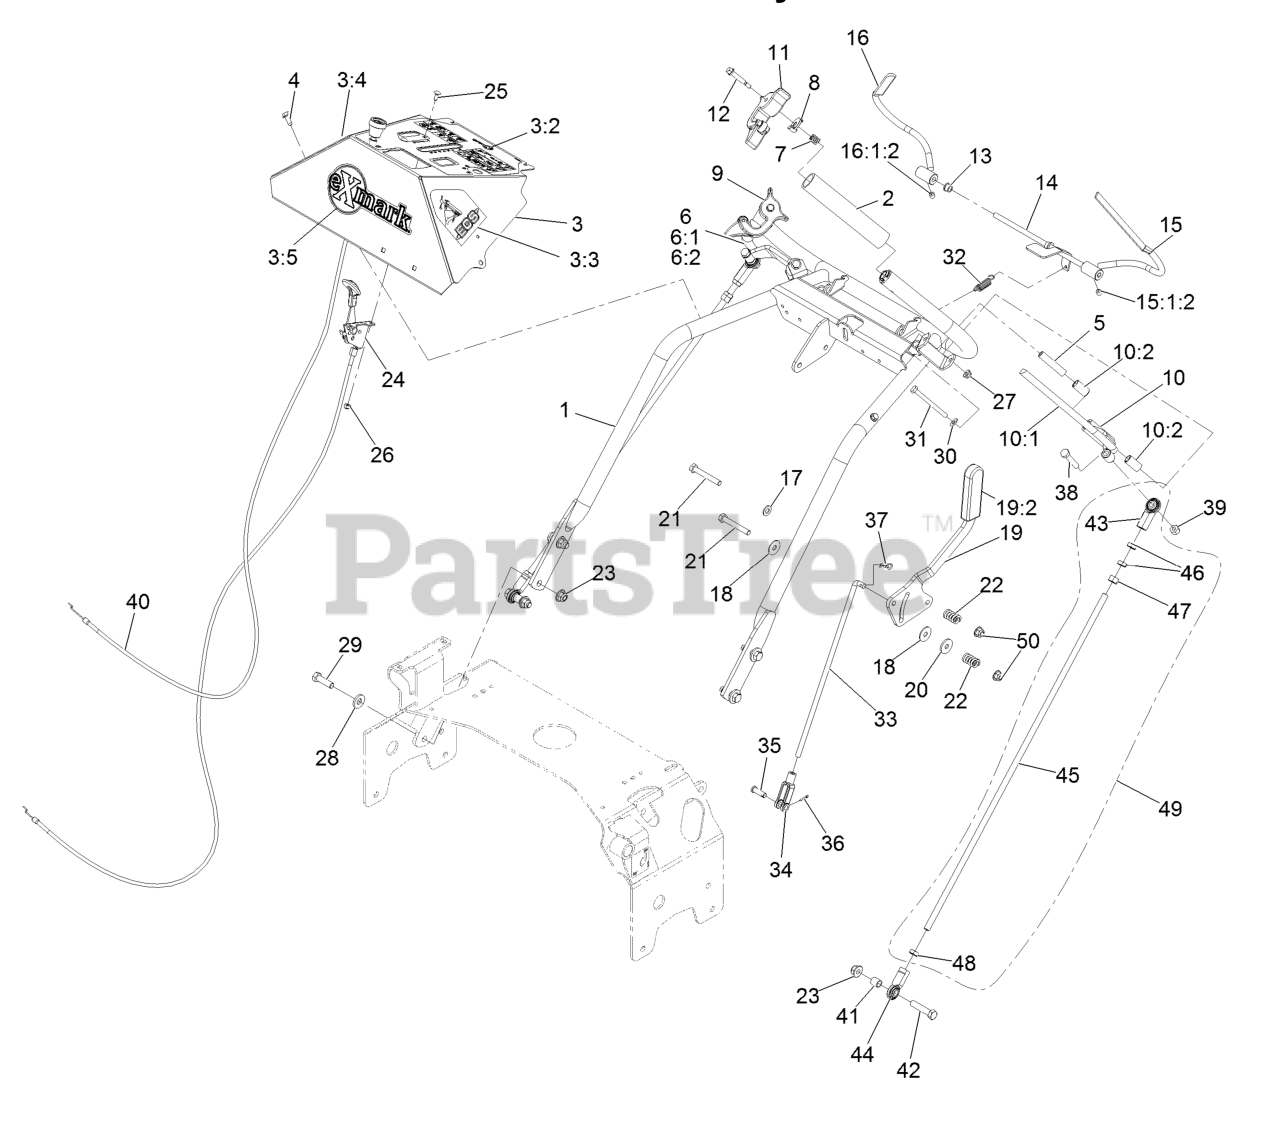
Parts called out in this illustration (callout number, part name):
1	WELD, HANDLE
2	GRIP-BAR, HANDLE
3	ASM, CONSOLE W/ DECALS
3:2	DECAL-CONSOLE TTX KAW
3:3	DECAL,LH ECS INSTRUCTION
3:4	DECAL,RH ECS INSTRUCTION
3:5	DECAL, EXMARK LOGO
4	SCREW-HWH
5	BUSHING-LEVER, DRIVE
6	DRIVE LEVER-ASM, RH
6:1	WLD,RH DRIVE LEVER
6:2	BUSHING, SLEEVE
7	SPRING-TANK, FUEL
8	LATCH, ECS
9	ASM,LATCH RH THUMB
10	DRIVE LEVER-ASM, LH
10:1	WLD,LH DRIVE LEVER
10:2	BUSHING, SLEEVE
11	ASM,LATCH LH THUMB
12	SCREW-SHOULDER
13	BUSHING-NYLON
14	WLD,OPC LEVER AXLE
15	WLD,LH OPC LEVER
15:1:2	SCREW-SET
16	WLD,RH OPC LEVER
16:1:2	SCREW-SET
17	WASHER-PLAIN
18	WASHER-FRICTION
19	LEVER, SHIFT W/GRIP
19:2	GRIP-HANDLE, STEERING
20	WASHER-FRICTION
21	SCREW-HH
22	SPRING-COMPRESSION
23	NUT-HF, NI
24	CONTROL-THROTTLE
25	BOLT-CARR
26	NUT-LOCK, NI
28	WASHER-BELLEVILLE
29	SCREW-HH
30	WASHER-FLAT
31	SCREW-HH
32	SPRING-EXTENSION
33	ROD,SPEED CONTROL
34	YOKE-ADJUSTABLE
35	PIN-CLEVIS
36	PIN-COTTER
37	PIN-COTTER
38	SCREW-HH
39	NUT-LOCK, NI
40	CABLE, CHOKE
41	SPACER-TUBE, PUMP LINK
42	SCREW-HH
43	JOINT-BALL, END
44	JOINT-BALL END, LH
45	LINK,DRIVE (PLTD)
46	NUT-HJ
47	NUT-HEX
48	NUT-HEX JAM, LH
49	DRIVE LINK ASM
50	NUT-HF, NI
